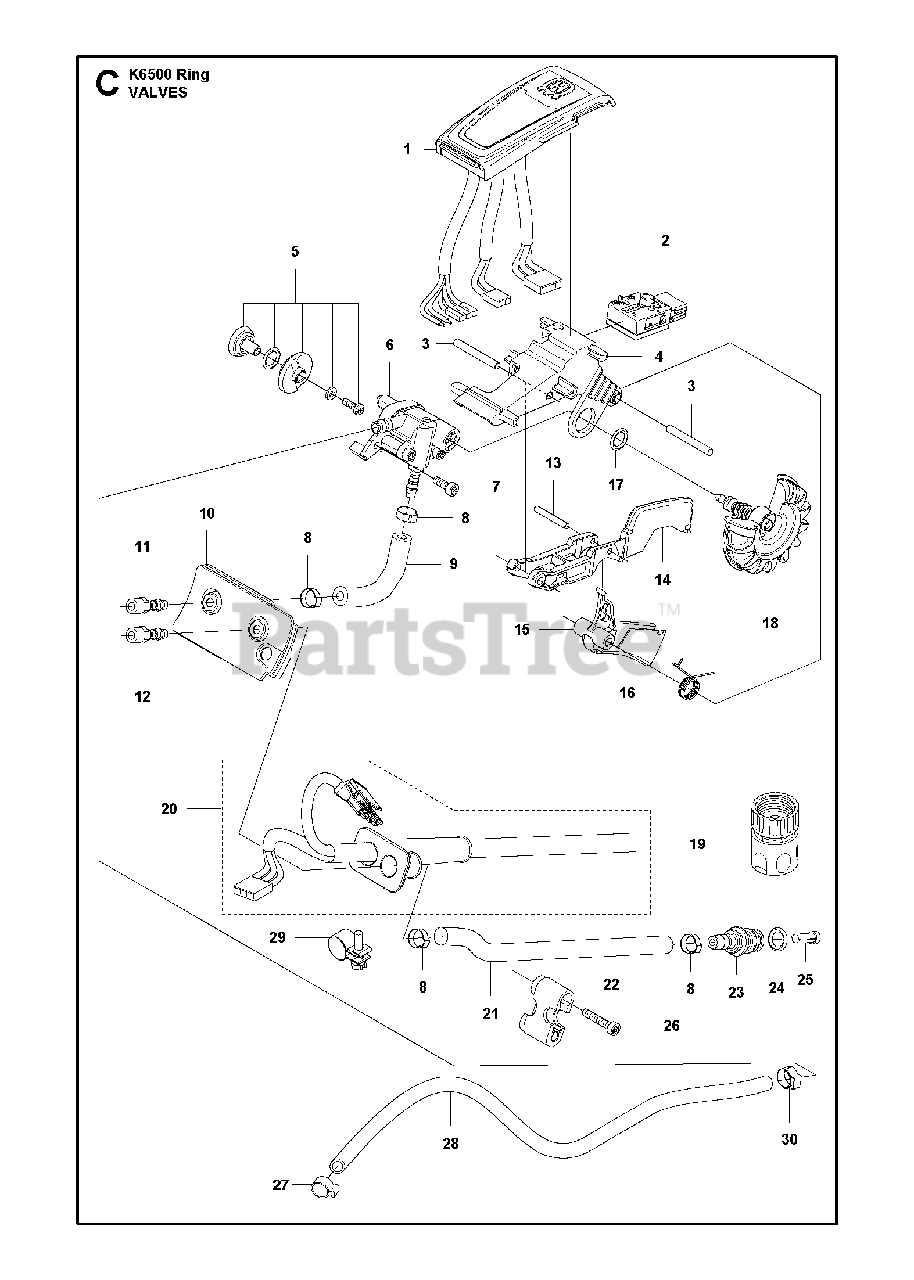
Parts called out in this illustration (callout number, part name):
3	PARALLEL PIN
7	SCREW ITXSCT
13	PARALLEL PIN
19	COUPLER"3/4"""
19	COUPLER"1/2"""
26	SCREW ITXSCT
27	HOSE CLAMP
29	HOSE CLAMP
